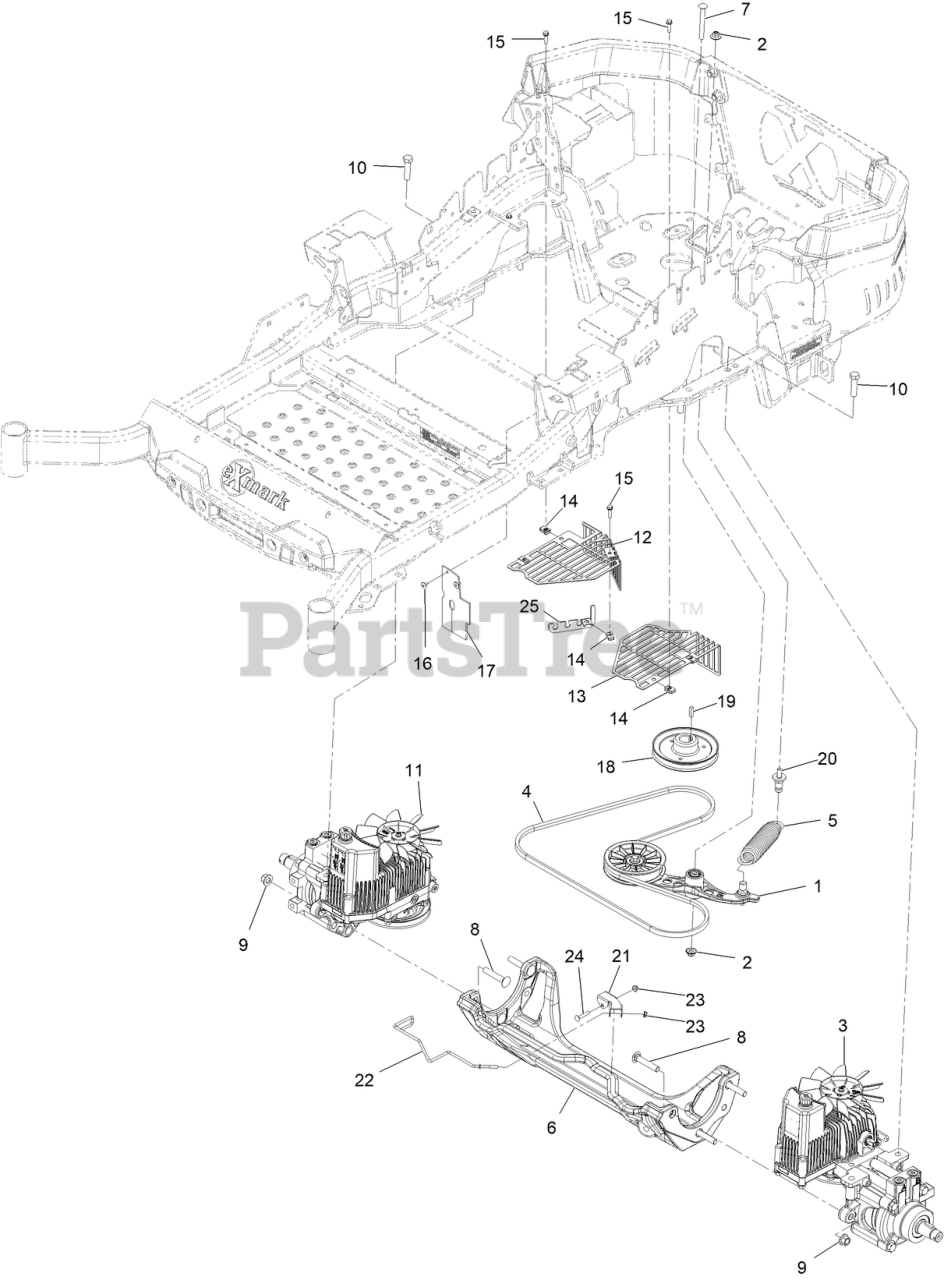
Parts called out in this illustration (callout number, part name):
1	PUMP IDLER ASM
2	Nut-Nyloc 3/8-16 Flg
3	HYDRO-LH
5	SPRING-EXTENSION
6	CRADLE-HYDRO
7	BOLT-SHOULDER, CARRIAGE 3/8-16 X 3 1/2
8	SCREW-CARR
9	Nut-Lock 1/2-13
10	SCREW-HH
11	HYDRO-RH
12	SHROUD-RH HYDRO
13	Shroud-LH Hydro [black]
15	SCREW-HHF
16	RIVET-POP
17	DEFLECTOR-AIR FLOW
18	SHEAVE-W/ HUB 5.81
20	Pin-Spring, Anchor
21	Bracket-U
22	Guide-Belt
24	SCREW-CARR
25	Clip-Vent Lines
